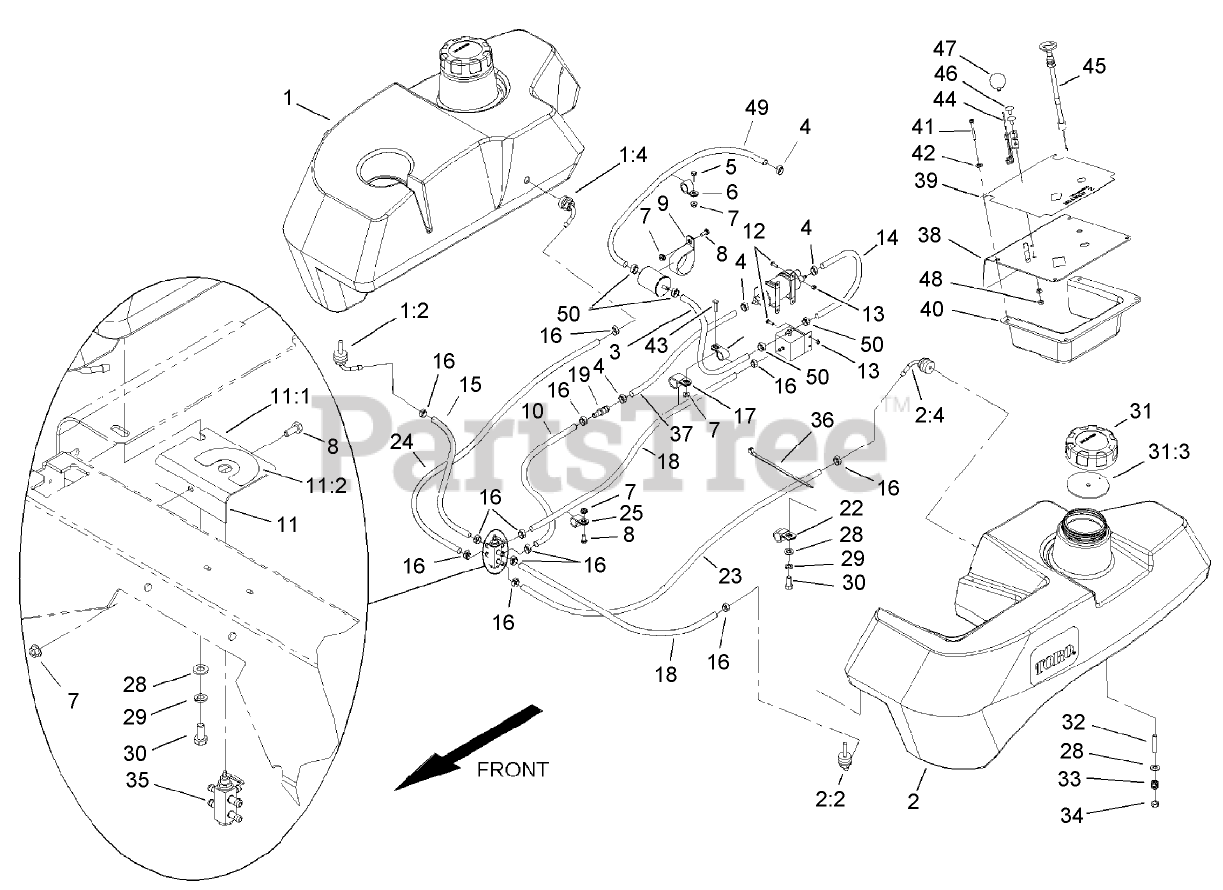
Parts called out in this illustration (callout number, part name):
1	RH Fuel Tank ASM
1:2	FITTING-FUEL, BULKHEAD
1:4	Fitting-Fuel, Bulkhead
2	LH Fuel Tank ASM
2:2	FITTING-FUEL, BULKHEAD
2:4	Fitting-Fuel, Bulkhead
3	Hose-Fuel
4	CLAMP-HOSE, FUEL
5	SCREW-HH
6	CLIP-LOOM
7	NUT-HF
8	SCREW-HH
9	CLIP-LOOM
10	HOSE-FUEL
11	Fuel Valve Bracket Asm
11:1	Bracket-Valve, Fuel
11:2	DECAL-VALVE, FUEL
12	SCREW-PPH
13	NUT-LOCK, NI
14	Hose-Fuel
15	HOSE-FUEL
16	CLAMP-HOSE, FUEL
17	CLIP-LOOM
18	HOSE-FUEL
19	Connector
23	Hose-Fuel
24	Hose-Fuel
25	CLIP-LOOM
28	WASHER-PLAIN
29	WASHER-LOCK
30	SCREW-HH
31	GAS CAP ASM
31:3	GASKET-CAP, GAS
33	SPRING-TANK, FUEL
34	NUT-LOCK, NI
35	VALVE-FUEL, DUAL FLOW
36	TIE-CABLE
37	HOSE-FUEL
38	Panel-Control
39	Decal-Panel, Control
40	SHIELD-PANEL, CONTROL
42	WASHER-SPRING
43	SCREW-HH
44	THROTTLE CABLE ASM
45	Control-Choke, Push / Pull
46	BOLT-CARR
47	KNOB-BALL
48	NUT-LOCK, NI
49	Hose-Fuel
